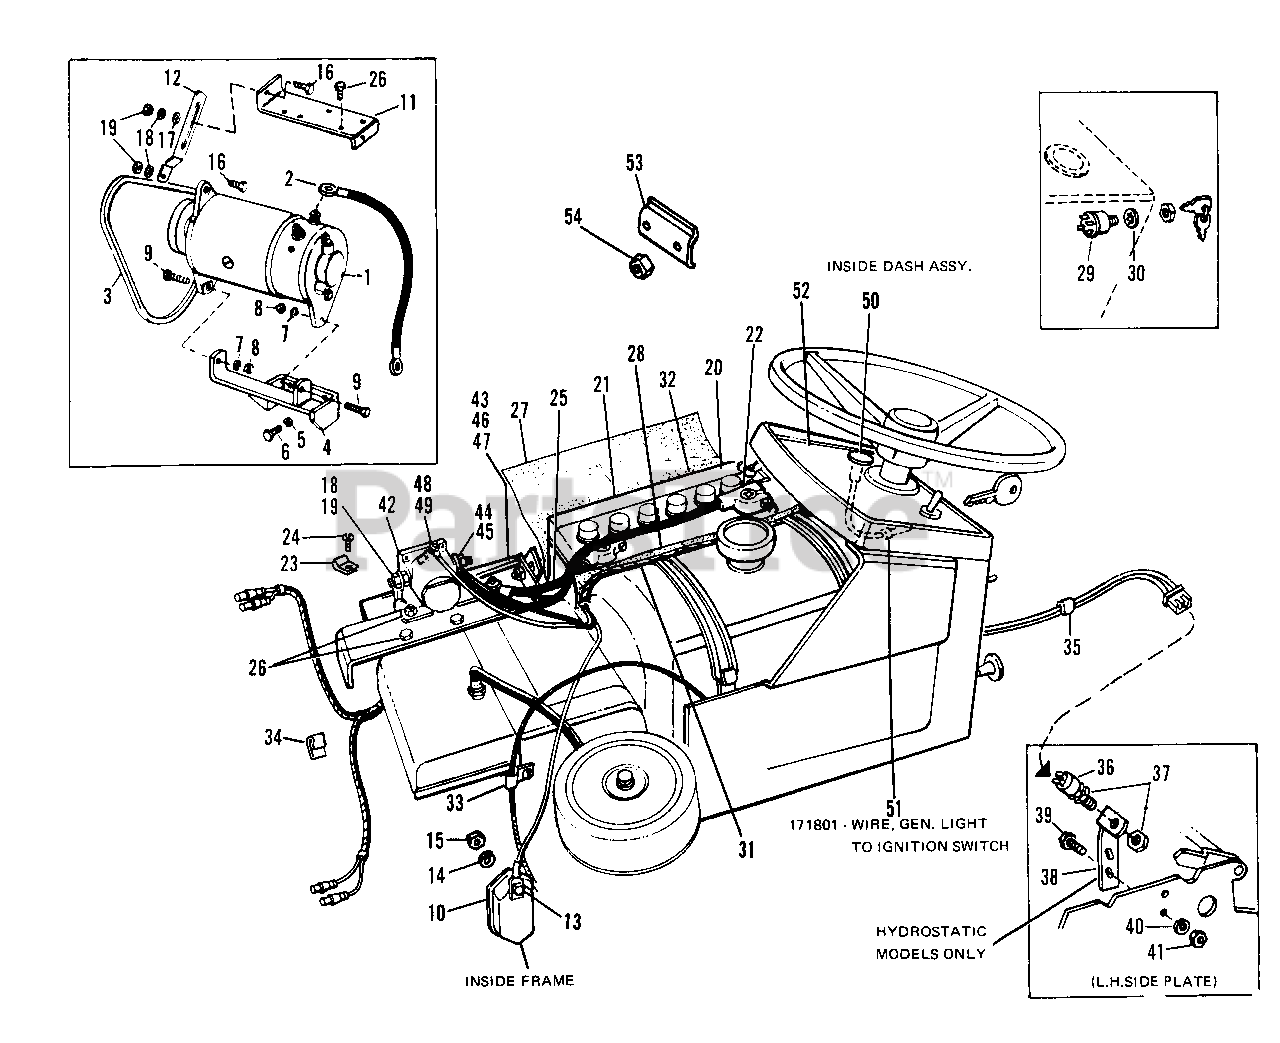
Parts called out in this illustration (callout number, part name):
1	Motor Generator
2	Generator Start Cable
3	V-BELT, 39.12"
4	Support Assy.
5	Lock Washer, 5/16"
6	Hex Cap Screw, 5/16"-18 x 3/4"
7	Lock Washer, 5/16"
8	Full Hex Nut, 5/16"-18
9	Hex Cap Screw, 5/16"-18 x 1-1/4"
10	Voltage Regulator
12	Belt Tightener
13	Hex Cap Screw, 1/4"-20 x 3/4"
14	Lock Washer, 1/4"
15	Full Hex Nut, 1/4"-20
16	Hex Cap Screw, 5/16"-18 x 3/4"
17	Plain Washer, 5/16"
18	Lock Washer, 5/16"
19	Full Hex Nut, 5/16"-18
21	Film, Battery
22	Cable (Battery to Solenoid)
23	Wire Clamp (Generator Cable)
24	Rd. Hd. Screw 10-24 x 1/2"
25	Cable (Battery to Ground)
26	Screw Hex Thread Forming, 1/4"-20 x 1/2"
27	Battery Insulation
28	Fuel Tank Insulation
29	Starter Switch w/Keys
30	Lock Washer Int., 9/16"
31	Harness Assembly
34	Speed Clip
36	Safety Switch
37	Nut
38	Switch Support
39	Hex Cap Screw, 5/16"-18 x 3/4"
40	Lock Washer, 5/16"
41	Full Hex Nut, 5/16"-18
43	Screw Hex Thread Forming, 1/4"-20 x 1/2"
44	Full Hex Nut, 10-32
45	Lock Washer, ext. No. 10
46	Full Hex Nut, 5/16"-18
47	Lock Washer, 5/16"
48	Lock Washer, 1/4"
49	Full Hex Nut, 1/4"-20
50	Indicator Lamp Assy.
51	Wire Ignition to Gen. Light
52	Circuit Breaker
53	Battery Clamp
